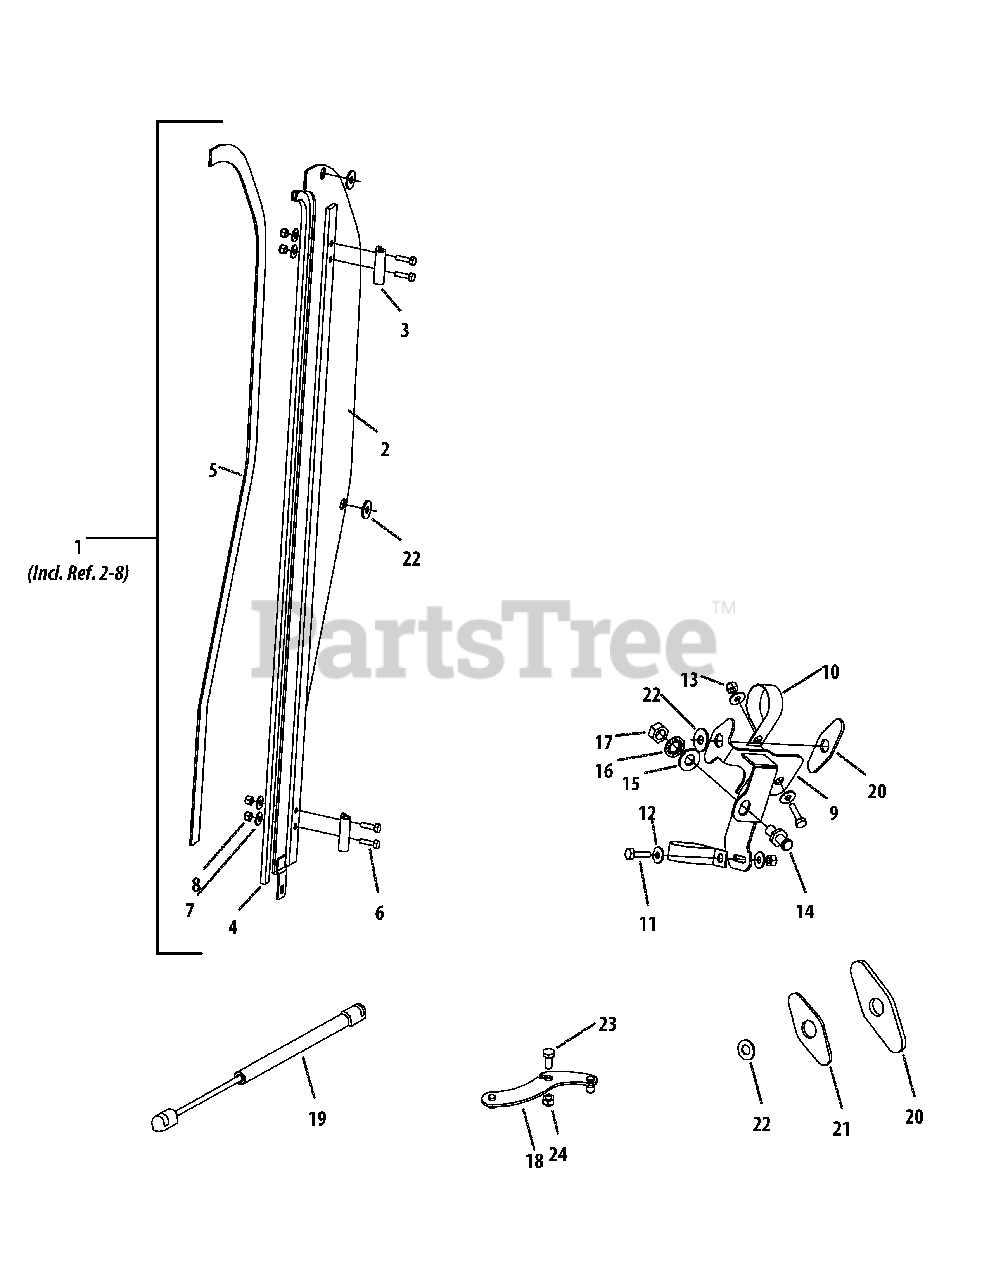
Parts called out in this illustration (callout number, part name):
1	Door Hng. Panel-L, (Incl. Ref. 2-8)
2	Hinge Panel
3	Tube Frame Hinge, 10 Gauge
4	Standard Trim Lock, 1/8" Grip
5	Foam Seal, 1" X 1/8
6	Hex Bolt, 1/4-20 x 1"
7	Washer, 1/4"
8	Lock Nut, 1/4-20
9	Door Striker - L
10	P Clamp
11	Hex Bolt, 1/4-20 x 1"
12	Washer, 1/4"
13	Lock Nut, 1/4-20
14	Striker Bolt For Rotary Latch
15	Washer, 1/2"
16	Lock Washer, 1/2"
17	M10 Nut
18	Door Frame Spring Mount, LH
19	Gas Spring (12") W/Quick Release
20	Rubber Door Filler, ROPS
21	S/M 2.75 X 1.25 Door Washer
22	Washer, 3/8"
23	Hex Bolt, 5/16-18 x 3/4"
24	Locknut, 5/16-18
